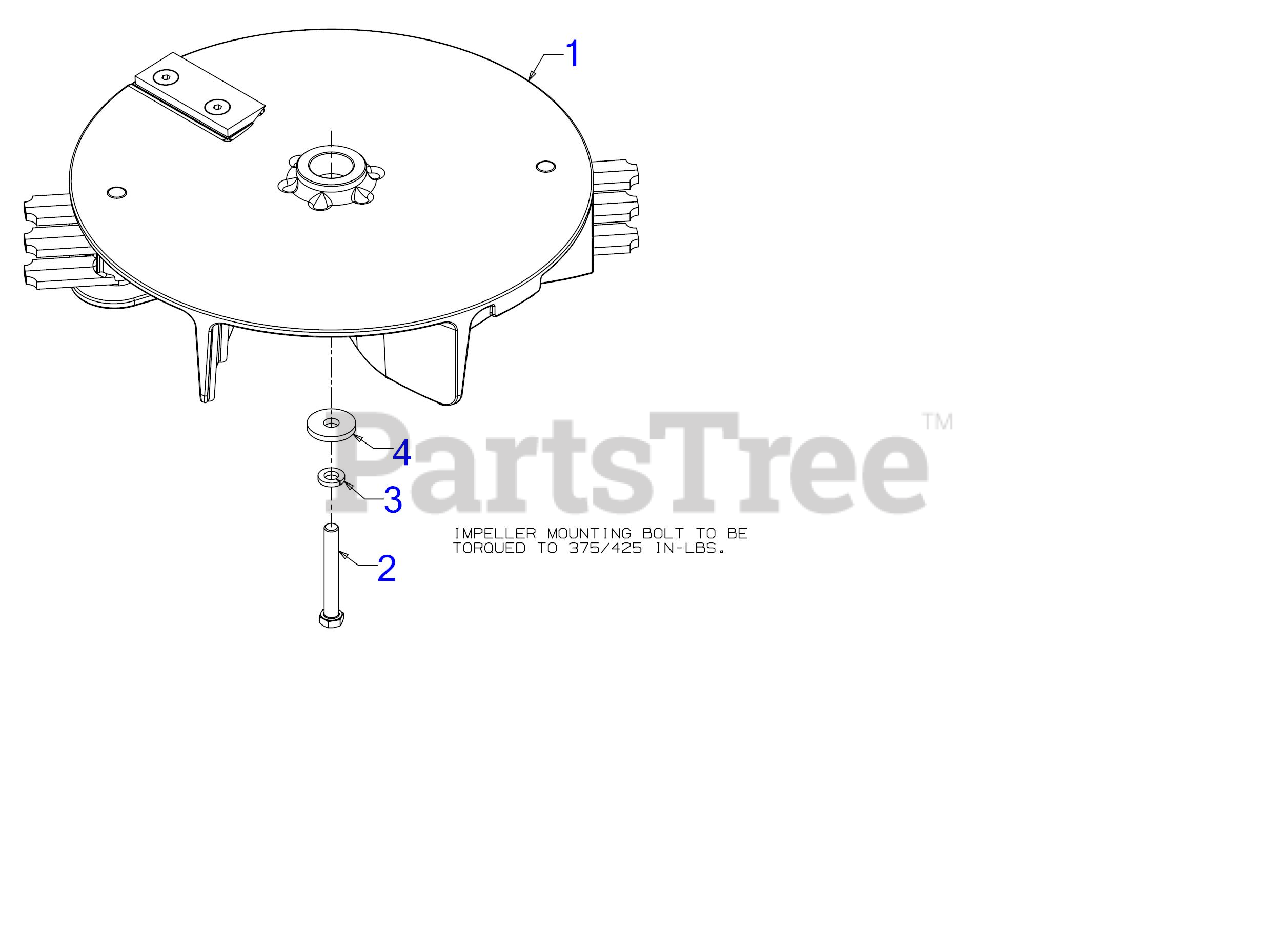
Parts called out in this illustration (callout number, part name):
1	IMPELLER ASSEMBLY
2	SCREW 3/8-24 x 2.75 GR5
3	LOCK WASHER 3/8HD
4	FLAT WASHER
